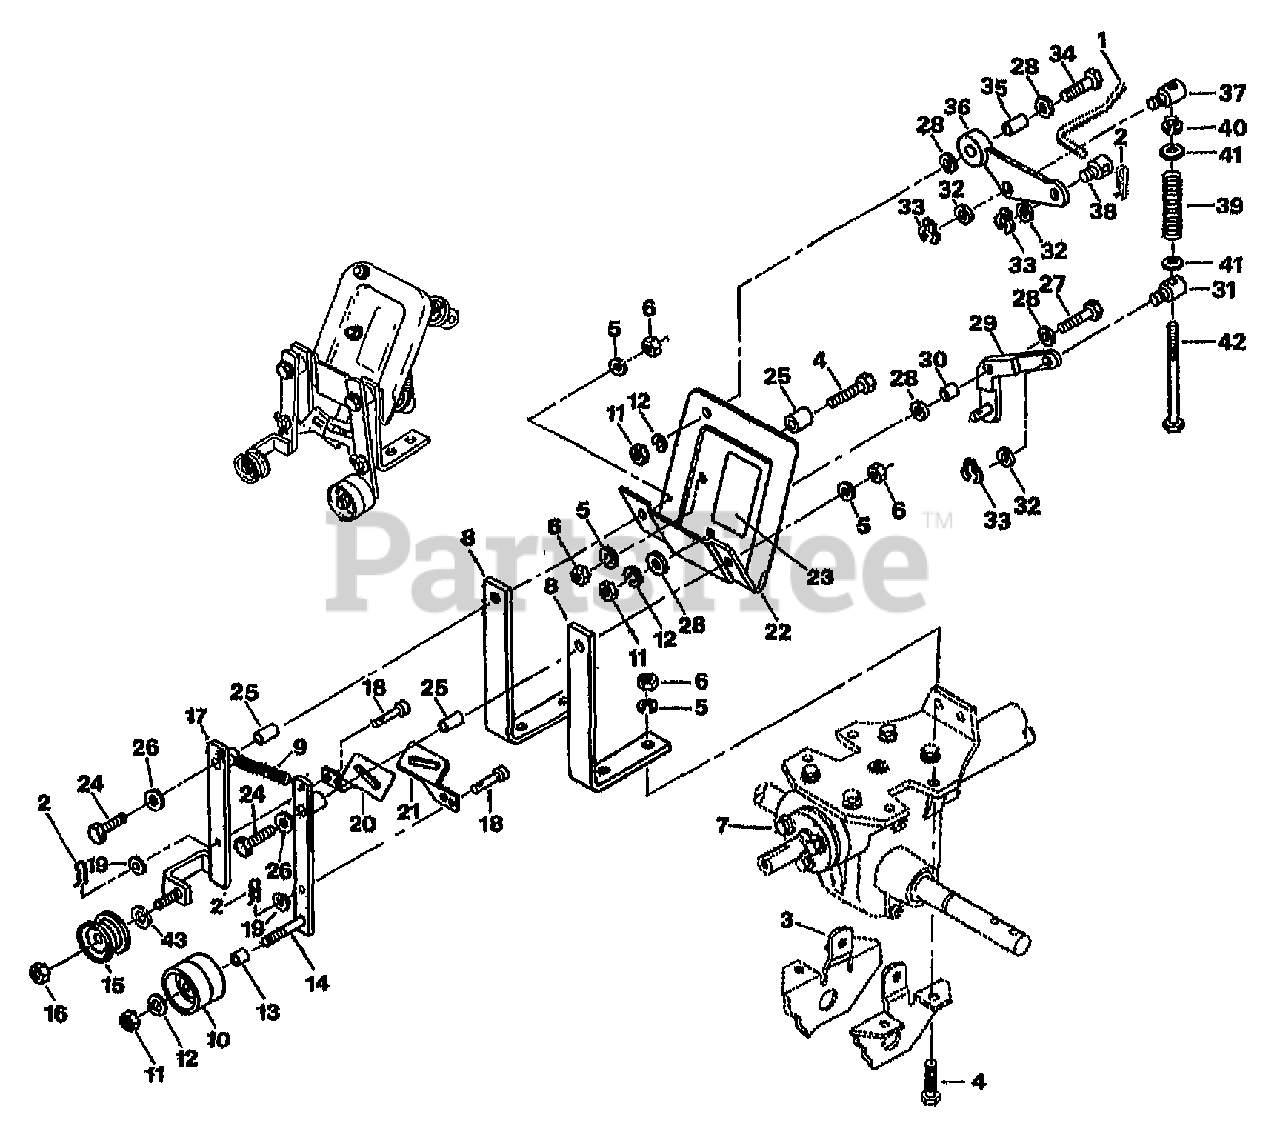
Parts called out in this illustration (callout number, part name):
1	ASSM-DR CONTROL ROD
2	PIN-COTTER .08 (2 also used w/ adj. shifting links.)
2	PIN-CLIP .08
3	BRKT-ENG JR RT W/GUSSET
4	SCR-HH 5/16-18X1.25 G5ZP
5	WASHER-LK .312 ZP
6	NUT-HEX 5/16-18 ZP
7	TRANS-REPLACE JR 2
8	BAR-MTG PNT
9	SPRING-.436 X 3.25
10	PULLEY-FWD IDLER
11	NUT-HEX 3/8-16 ZP
12	WASHER-LK .375 @ DEPL
13	BUSHING-.5X.375X.3
14	ARM-IDLER FWD PNT
15	IDLER-REV (Use with P/N 9807 Locknut)
16	NUT-LOCK 3/8-16 NYLON ZP
17	ASSM-IDLER REV @ DEPL
18	PIN-CLEVIS .375X.719 ZP
19	WASHER-FLAT 1/4 SAE
21	LINK-FWD
22	BASE-SHIFTING (Forward/Reverse - inc. # 23)
23	DECAL-BELT WARNING
24	BOLT-HH 5/16-18 X 2 G5 ZP
25	BUSHING-.438X.323X.712
26	WASHER-#.75X.32X.09 ZP
27	SCR-HH 3/8-16X1.25
28	SPACER-.88X.385X.09 ZP
29	BELLCRANK-WELDMENT
30	BUSHING-.5X.38X.4
31	PIVOT-SLIDE
32	WASHER-#.88X.51X.063 ZP
33	RING-KLIP .500 ZINC
34	BOLT-HH 3/8-16X1.5 FTH ZP
35	BUSHING-.5X.38X.665
36	RODCRANK (Use with P/N 9060 Bushing only)
37	PIVOT-THREADED
38	PIVOT-ROD
39	SPRING-.52 X 3
40	RING-KLIP 5304-25
41	WASHER # ZP
42	SCR-HH 1/4-20X4.5 G5
43	BUSHING-.54X.38X.08
